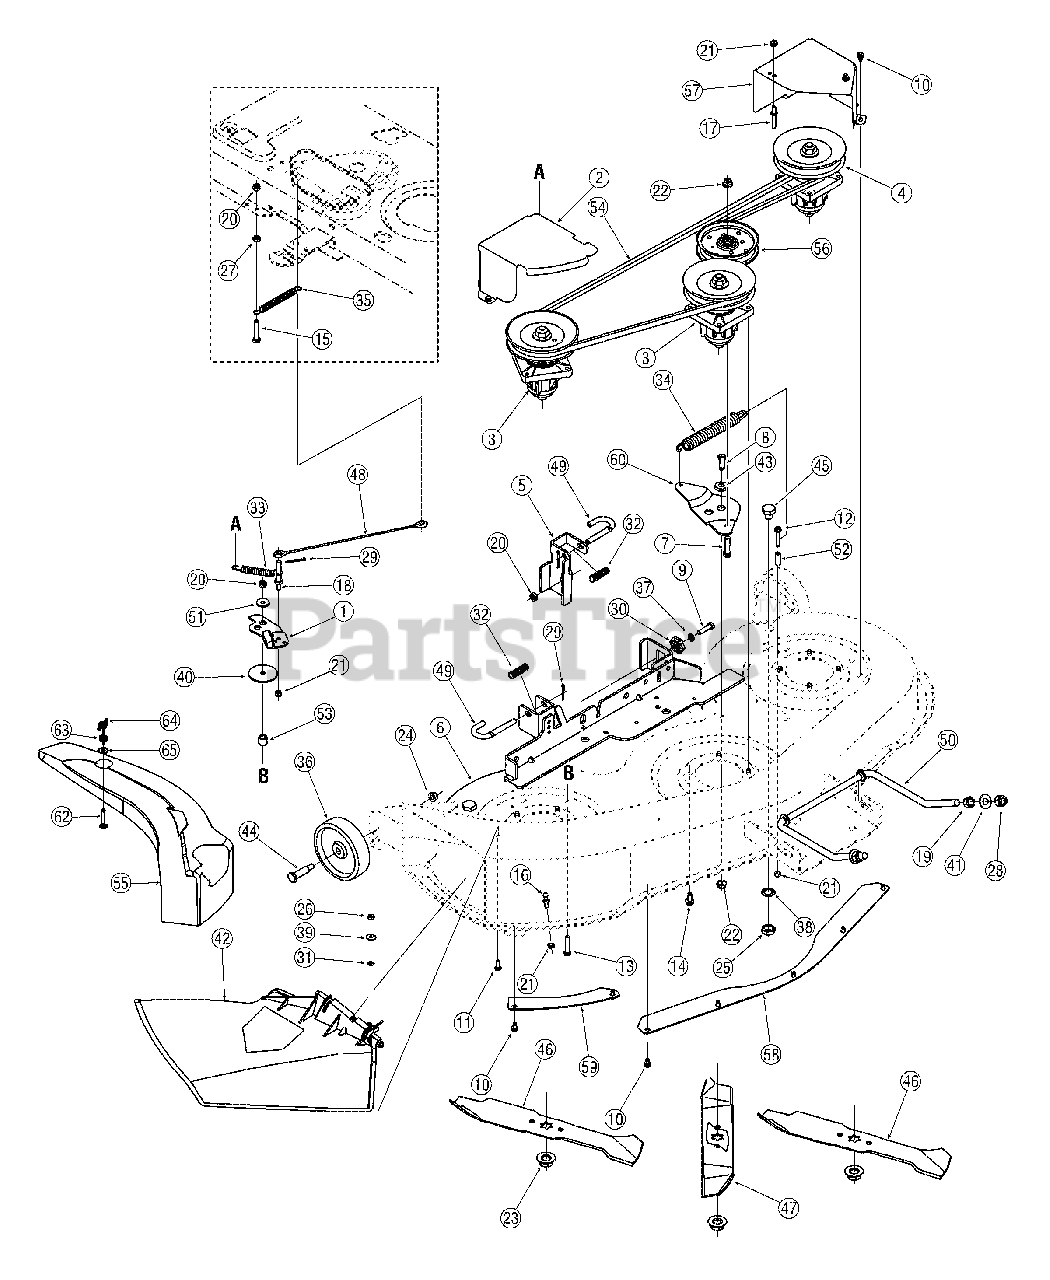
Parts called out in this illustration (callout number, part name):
1	Brake Assembly, Deck
3	Spindle Assembly, 5.00 Dia.
4	Spindle Ass'y, Double Pulley
7	Screw, 3/8-16, 1.50, Gr5
8	Screw, 3/8-16, 1.00, Gr5
9	Screw, 5/16-18, 1.25, Gr5
10	Screw, 1/4-20, 0.500
11	Screw, 1/4-20 x.75, Gr5
12	Screw, 1/4-20, 1.500
13	Screw, 5/16-18, 1.50, Gr5
14	Screw, Ld, 5/16-18, 0.750
15	Screw, 5/16-18, 1.75, Gr5
16	Pin, Grass catcher, 1/4-20
17	Belt Guard Pin 1/4 Dia x 1.43
18	Pin, 1/4-20, 3/8 x 2.0
19	Nut, Hex, 1/2-13, Gr5
20	Nut, Flange Lock, 5/16-18, Gr F, Nylon
21	Nut, Flange Lock, 1/4-20, Gr F, Nylon
22	Nut, Flange Lock, 3/8-16, Gr F, Nylon
23	Nut, Flange, 5/8-18
24	Nut, Flange Lock, 3/8-16, Gr F
25	Nut, Hex, M16-1.5
26	Nut, Hex, 1/4-20, Gr5
27	Nut, Hex, 5/16-18, Gr5
28	Nut, Hex Lock, 1/2-13, Gr8, Nylon
29	Pin, Cot, 1/8 x 1.25
30	Adjustment Gear, Deck
31	Nut, Push,.25 ID x.50 OD
32	Spring, Compression,.531 OD x 1.75
33	Spring, Extension,.50 Dia x 3.97
34	Spring, Extension,.91 Dia x 7.33
35	Spring, Extension,.68 OD x 5.00 Lg
36	Wheel, Deck 5.0 x 1.38
37	Washer, Lock, 5/16
38	Washer, Lock, 5/8
39	Washer, Bell,.265 x.75 x.062
40	Washer, Flat,.34 x 2.25 x.10
41	Washer, Flat,.51 x 1.12 x.06
42	Chute Assembly
43	Spacer, Shoulder,.625 ID x.169
44	Spacer, Shoulder,.498 x 1.53, 3/8-16
45	Plug, Screw, M16 x 1.5
46	Blade, 16.28", Star 3-in-One
47	Blade, 14.88", Star 3-in-One
48	Cable, 12.00"
49	Rod, Deck Release
50	Rod, Deck
51	Shoulder Spacer
52	Spacer,.260 x.372 x 1.030
53	Spacer,.375 x.63 x.595
54	Belt, V-Type, Poly
55	Mulch Plug
56	Pulley, Idler, 4.25" Dia.
62	Screw, 1/4-20 x 1.500
63	Hex Nut, 1/4-20
64	Wing Nut, 1/4-20
65	Flat Washer,.28 x.74 x.063
